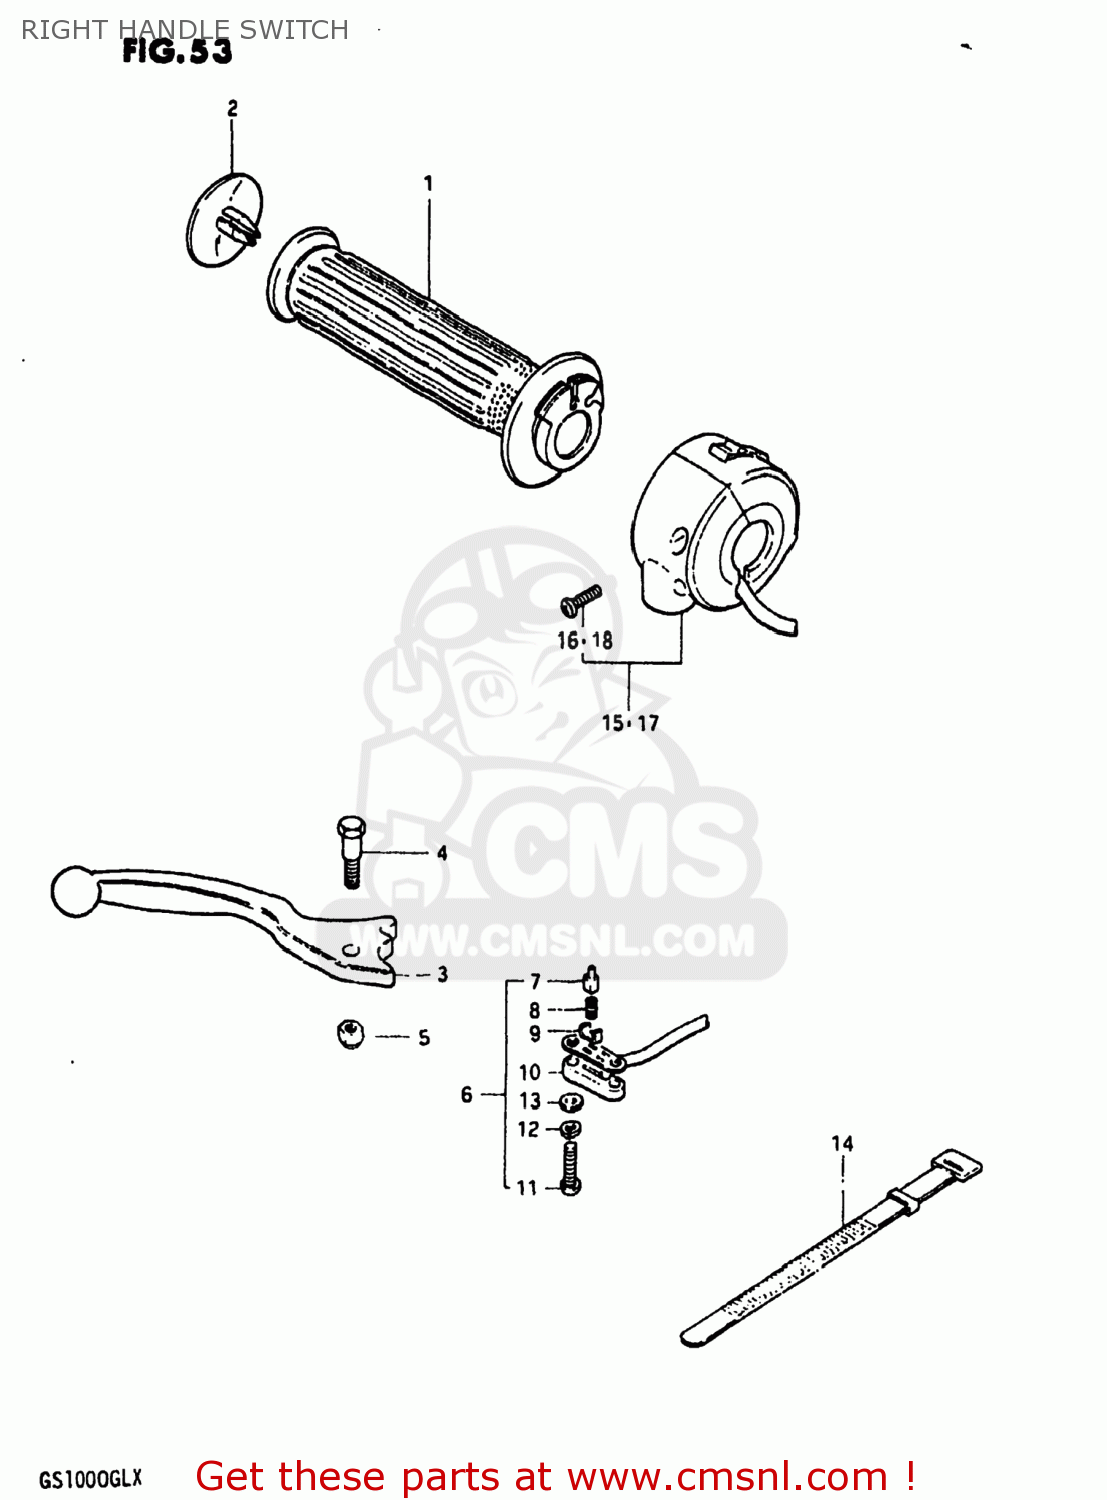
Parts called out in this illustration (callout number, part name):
1	GRIP,THROTTLE
2	CAP,GRIP END
3	LEVER,BRAKE
4	BOLT
5	NUT 6MM
6	SWITCH ASSEMBLY
7	HOLDER
8	SPRING
9	PLATE
10	COVER,FR BK TERMINAL BASE
11	SCREW
12	LOCK WASHER
13	WASHER
14	CLAMP(L:120)
15	SWITCH ASSEMBLY,HANDLE,RIGHT
16	SCREW
17	SWITCH ASSEMBLY,HANDLE,RIGHT
18	SCREW
